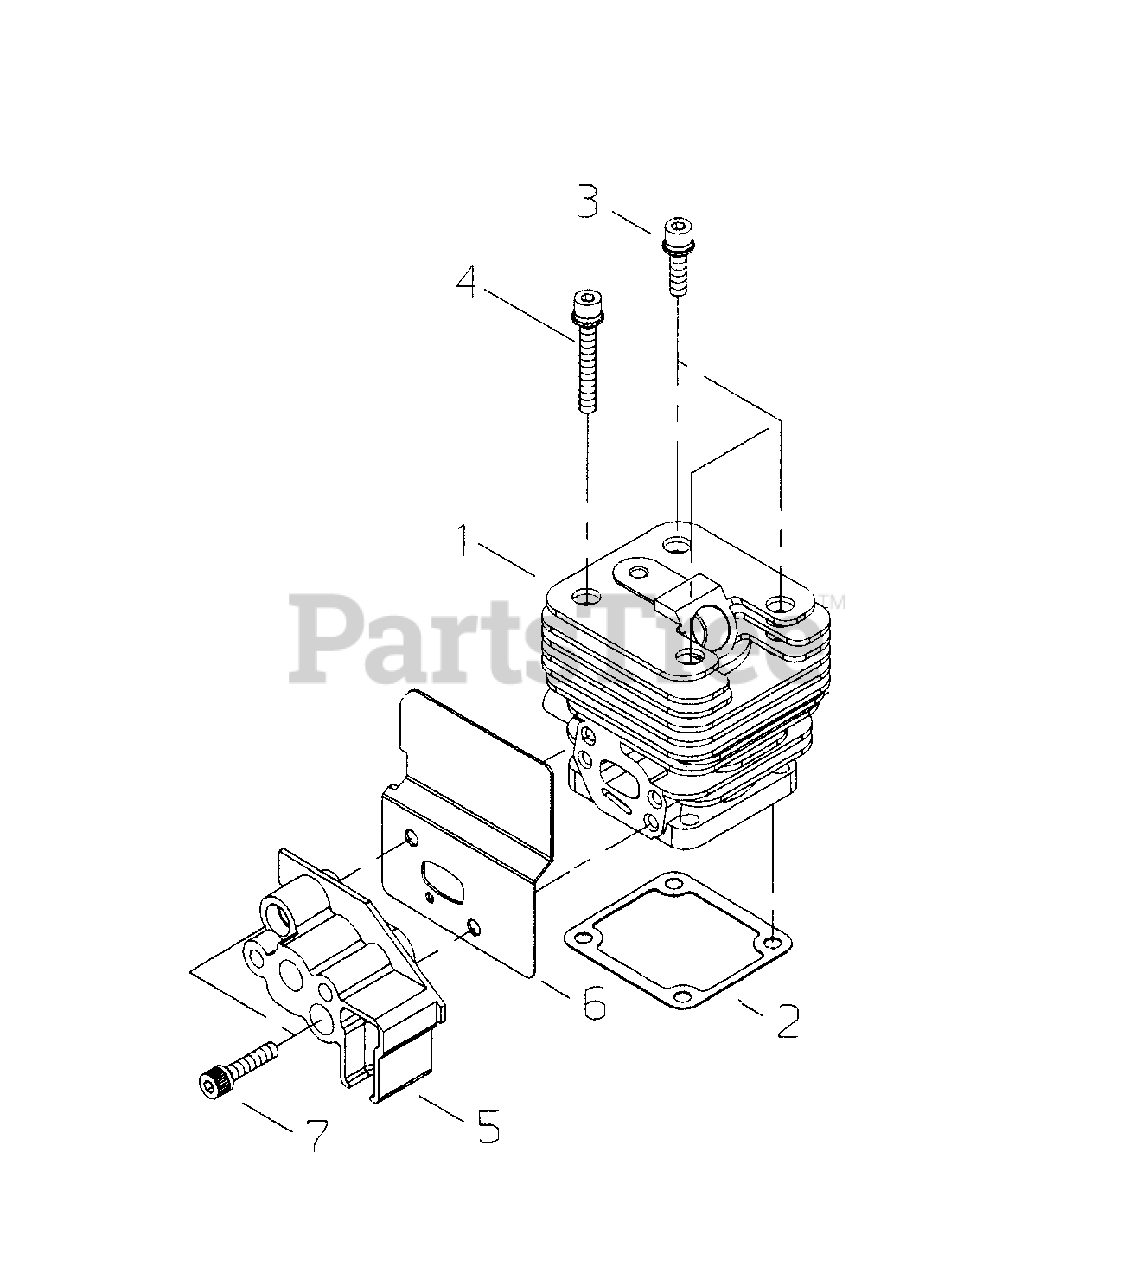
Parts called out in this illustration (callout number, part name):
1	CYLINDER
2	GASKET, CYLINDER
3	SCREW - 5X16
4	SCREW - 5X35
5	INSULATOR
6	GASKET
7	SCREW - 5X30
